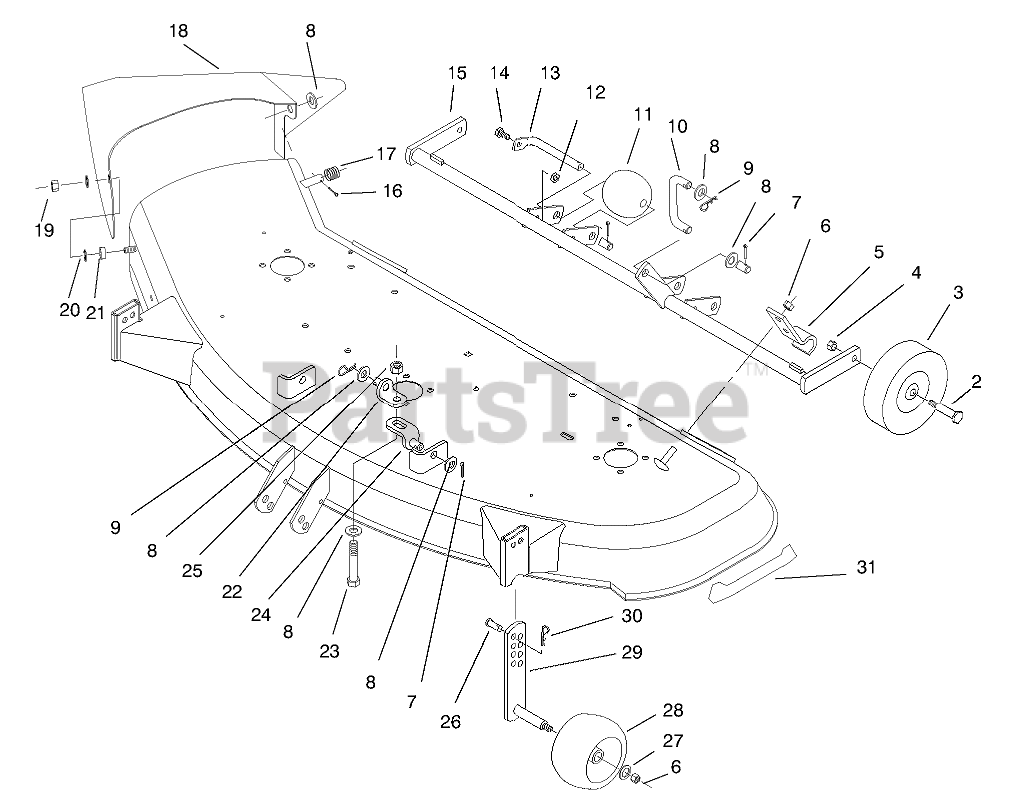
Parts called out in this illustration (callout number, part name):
1	BOLT-CARR
1	BEARING
2	BOLT-SHOULDER
3	WHEEL
4	NUT-HEX
5	BRACKET-PIVOT
6	NUT-LOCK, NI
7	PIN-COTTER
8	WASHER-FLAT
9	PIN-COTTER, HAIR
10	LINK-REAR
11	ROLLER
12	NUT-LOCK, NI
13	SHAFT-ROLLER
14	SCREW-HH
15	SUPPORT-GAGE WHEEL
16	PIN-COTTER
17	SPRING-DEFLECTOR
18	Chute / Decal Asm
19	NUT-HJ
20	WASHER
21	BUSHING-PIVOT
22	BRACKET-LIFT, UPPER
23	SCREW-HH
24	BRACKET-LIFT, LOWER
25	NUT-JAM
26	PIN-CLEVIS
27	WASHER-FLAT
28	WHEEL-GAGE
29	GAGE-WHEEL
30	PIN-HAIR
31	DECAL-RECYCLER
